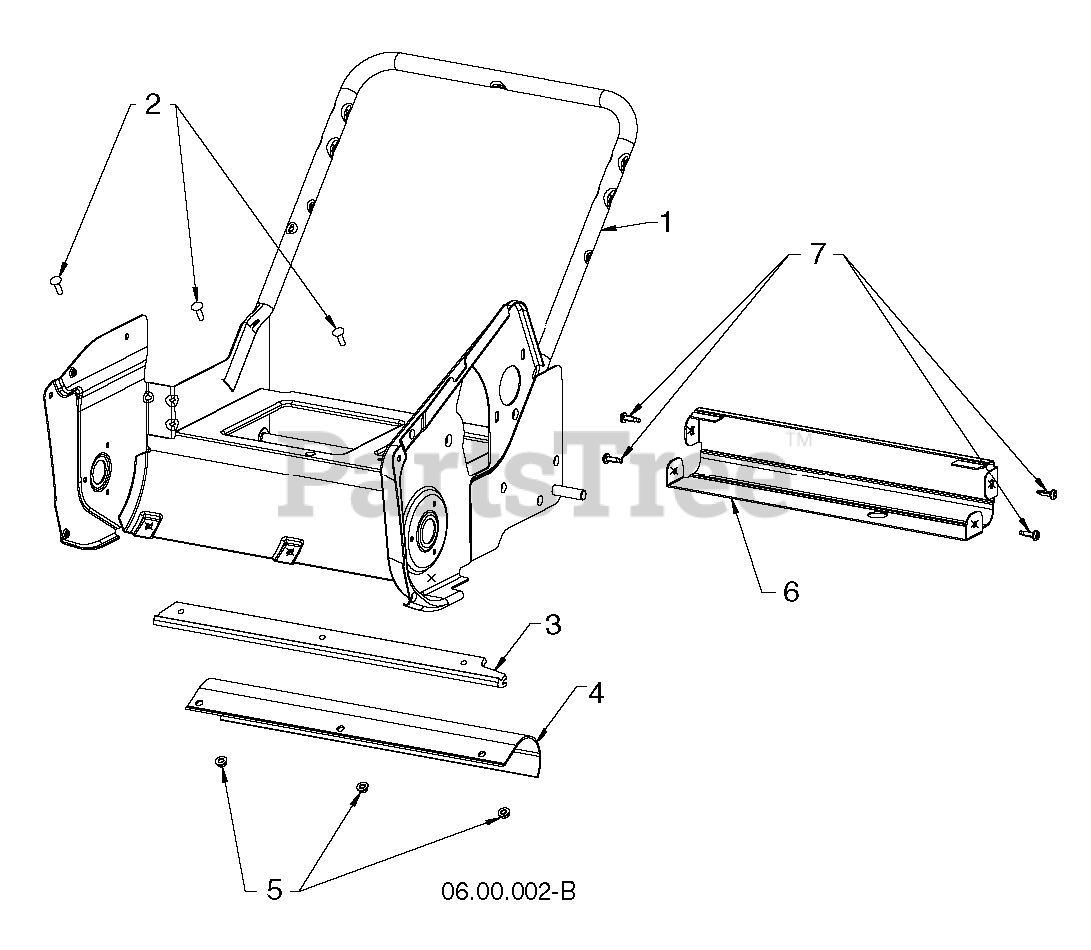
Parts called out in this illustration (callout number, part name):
1	FRAME.WELDMENT.GREY
2	BOLT.CARRIAGE.1/4-20 X 7/8
3	BAR.SCRAPER.SINGLE.STAGE.GREY
4	SKIRT.SCRAPPER-SSST
5	NUT.HEX.FLANGE.1/4
6	SUPPORT.SSST.REAR.FRAME.GREY
7	SCREW.PAN.HD.TORX.1/4-20X.750
